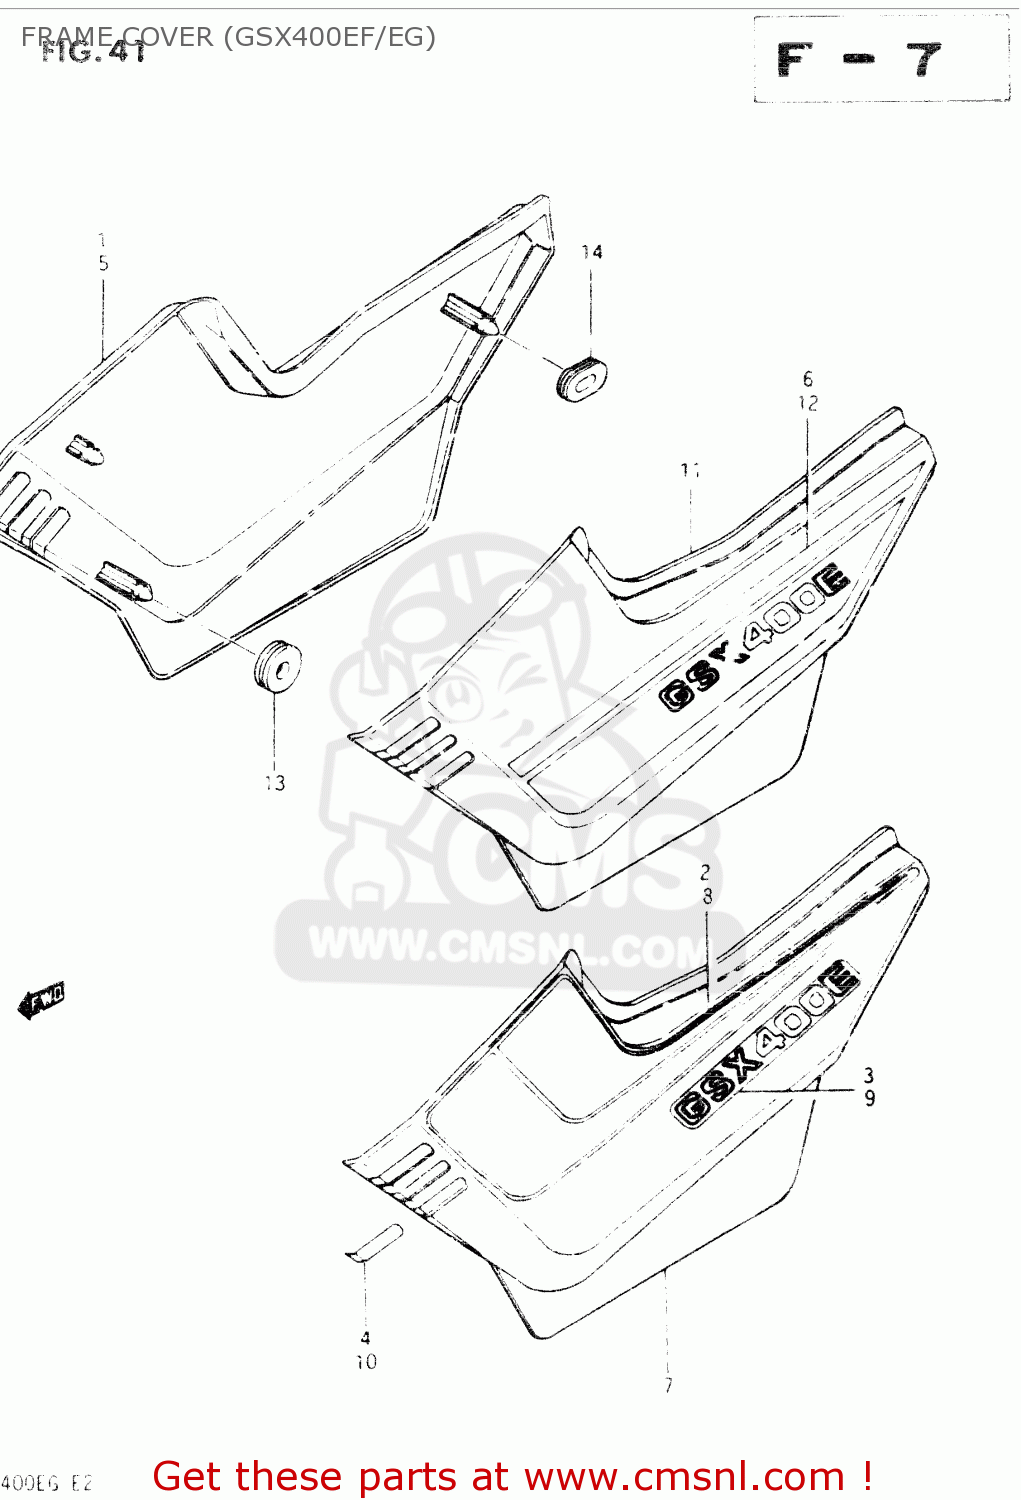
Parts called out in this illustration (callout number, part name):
1	COVER , FRAME RH (RED)
2	TAPE SET, FRAME COVER RH
3	EMBLEM (WHITE)
4	LABEL,FRAME COVER DENT,R
5	COVER, FRAME RH (WHITE)
6	TAPE SET,FRMC,
7	COVER, FRAME LH (RED)
8	TAPE SET, FRAME COVER LH
9	EMBLEM (WHITE)
10	LABEL,FRAME COVER DENT
11	COVER, FRAME LH (WHITE)
12	TAPE SET, FRAME COVER LH
13	CUSHION
14	CUSHION
